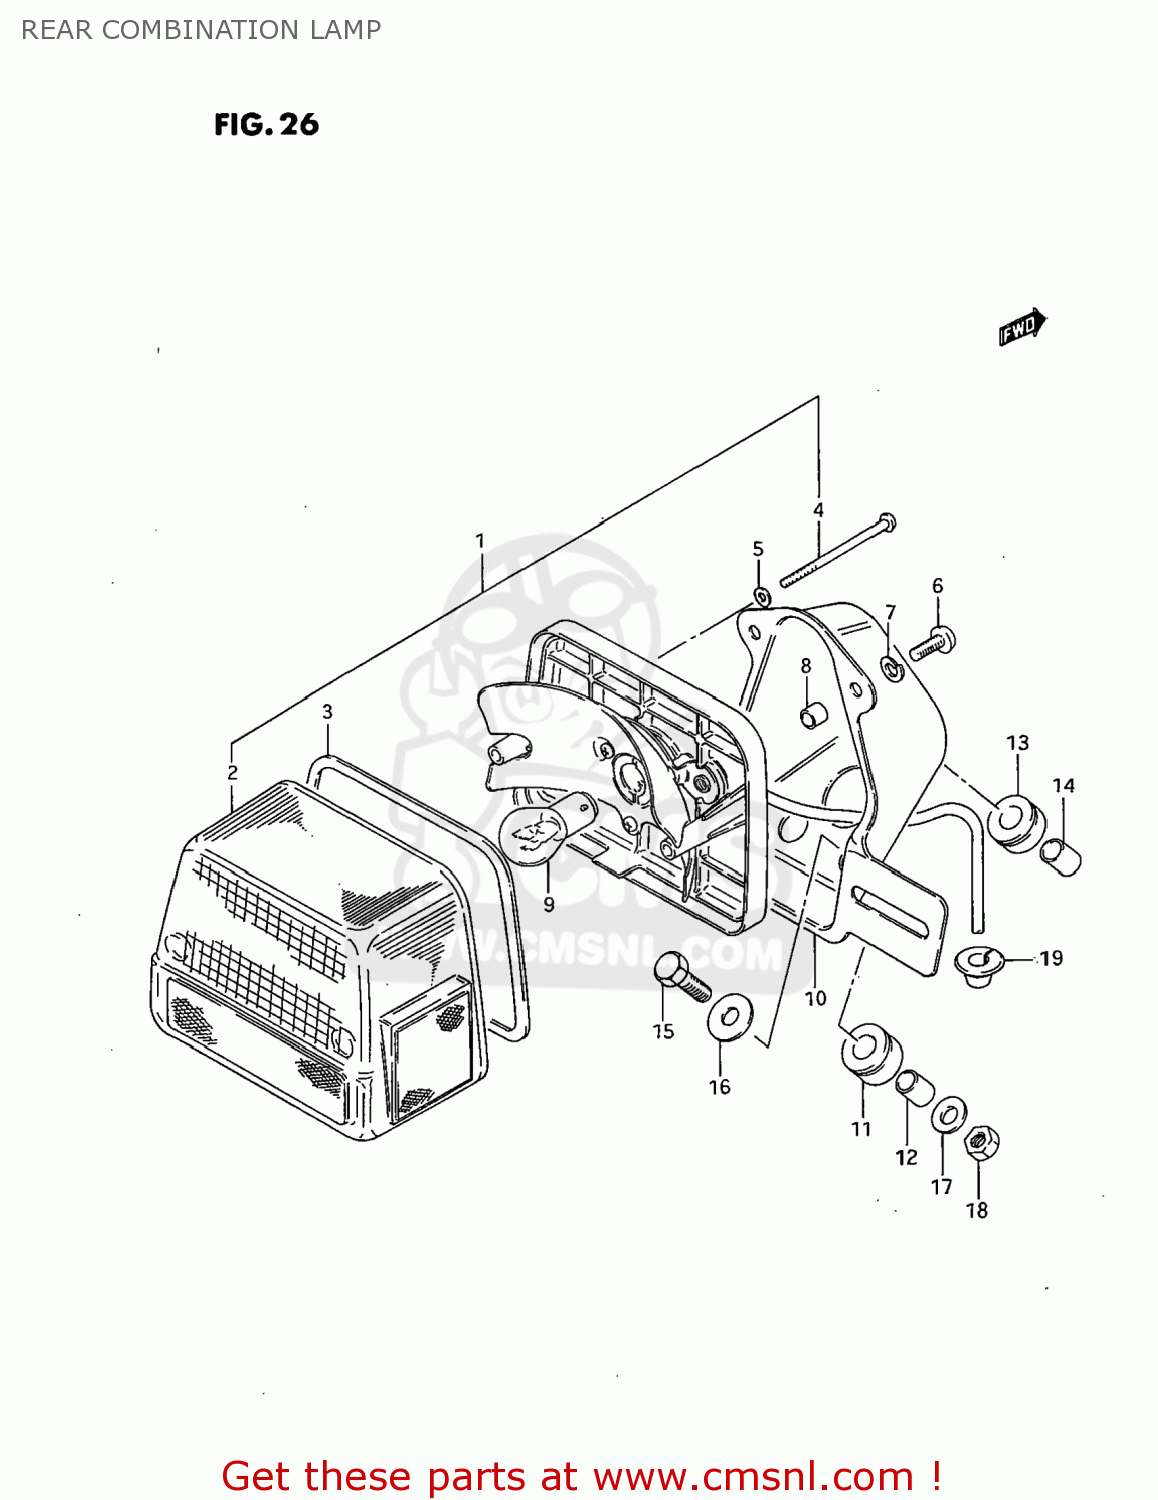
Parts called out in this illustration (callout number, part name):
1	LAMP UNIT,RR COMBNATION
2	LENS
3	GASKET (NAS)
4	SCREW
5	GASKET (NAS)
6	SCREW
7	LOCK WASHER
8	SPACER
9	BULB(12V23W)
10	BRACKET,REAR COMBINATION LAMP
11	CUSHION,REAR COMBINATION LAMP
12	SPACER,REAR COMBINATION LAMP
13	CUSHION
14	SPACER
15	BOLT
16	WASHER (6.5X20X1.2)
17	WASHER, LOWER
18	NUT
19	GROMMET
